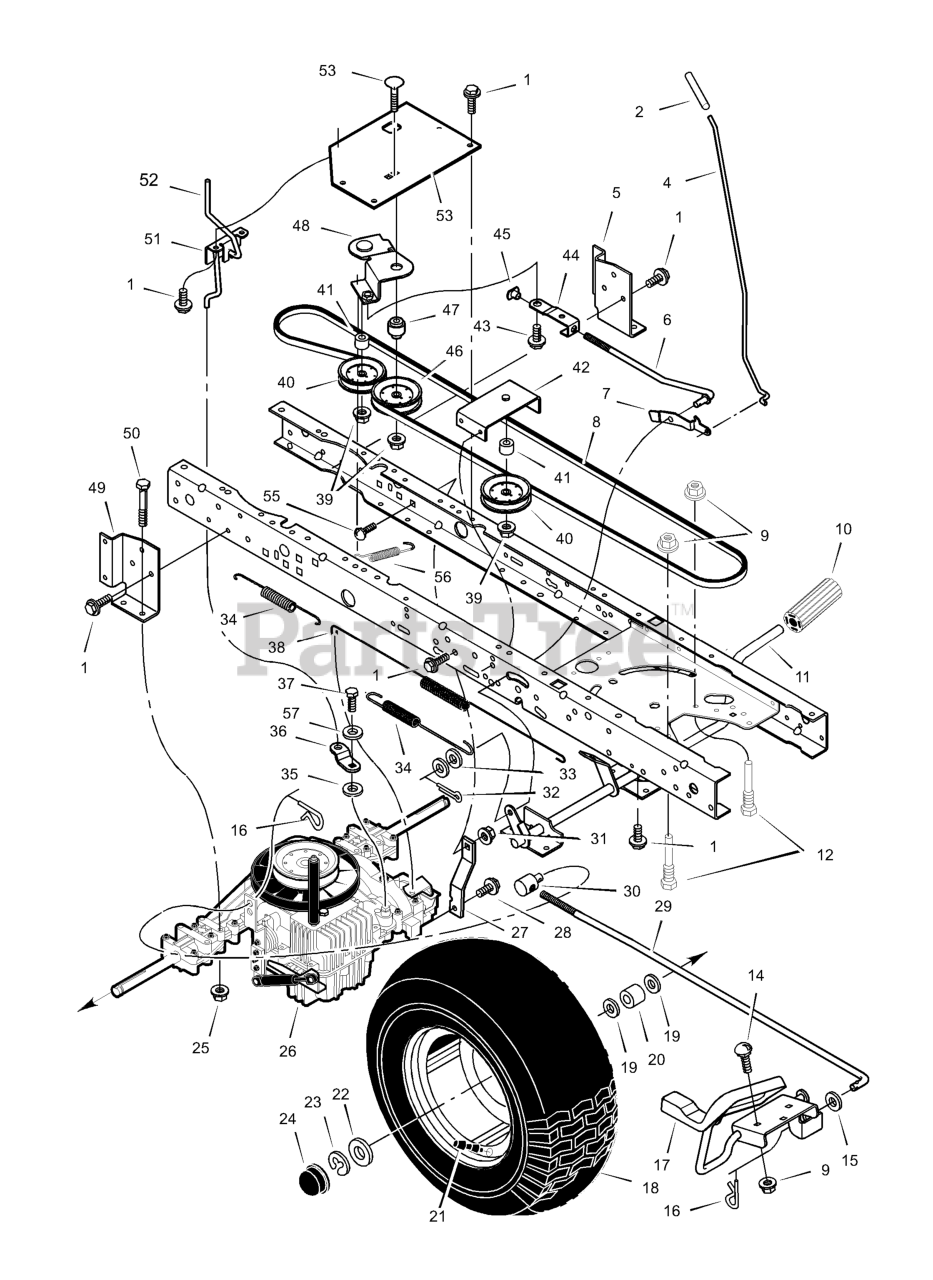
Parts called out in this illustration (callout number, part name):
2	Grip, Parking Brake
4	Rod, Parking Brake
5	Bracket, Transaxle - Left
6	Rod, Clutch
7	Latch, Parking Brake
8	V-Belt, Drive
9	Nut, Flange
10	Pedal, Brake/Clutch
11	Assembly, Brake Pedal
12	Screw, Guide
14	Bolt, Carriage
16	Pin, Hair
17	Pedal Assembly, Hydro
18	Wheel & Tire Ass'y - Rear 20"
20	Spacer
21	Stem, Valve
24	Cap, Hub
25	Nut, Centerlock
26	Transaxle **
27	Strap, Torque
29	Rod, Control
30	Nut, Adjusting
31	Nut, Centerlock
32	Pin, Cotter
34	Spring, Extension
36	ARM, Disconnect
37	Capscrew
38	Spring, Brake
39	Locknut, Flange
40	Pulley, Idler
42	Bracket, Idler Assembly
43	Bolt, Shoulder
44	Link, Clutch
45	Nut, Tee
46	Pulley, Idler
47	Bushing, Pivot
48	Arm Assembly, Idler
49	Bracket, Transaxle -Right
50	Bolt, Hex
51	Bracket, Disconnect
52	Rod, Disconnect
53	Bracket, Idler Pivot
54	Bolt, Carriage
55	Bolt, Carriage
56	Spring, Clutch
